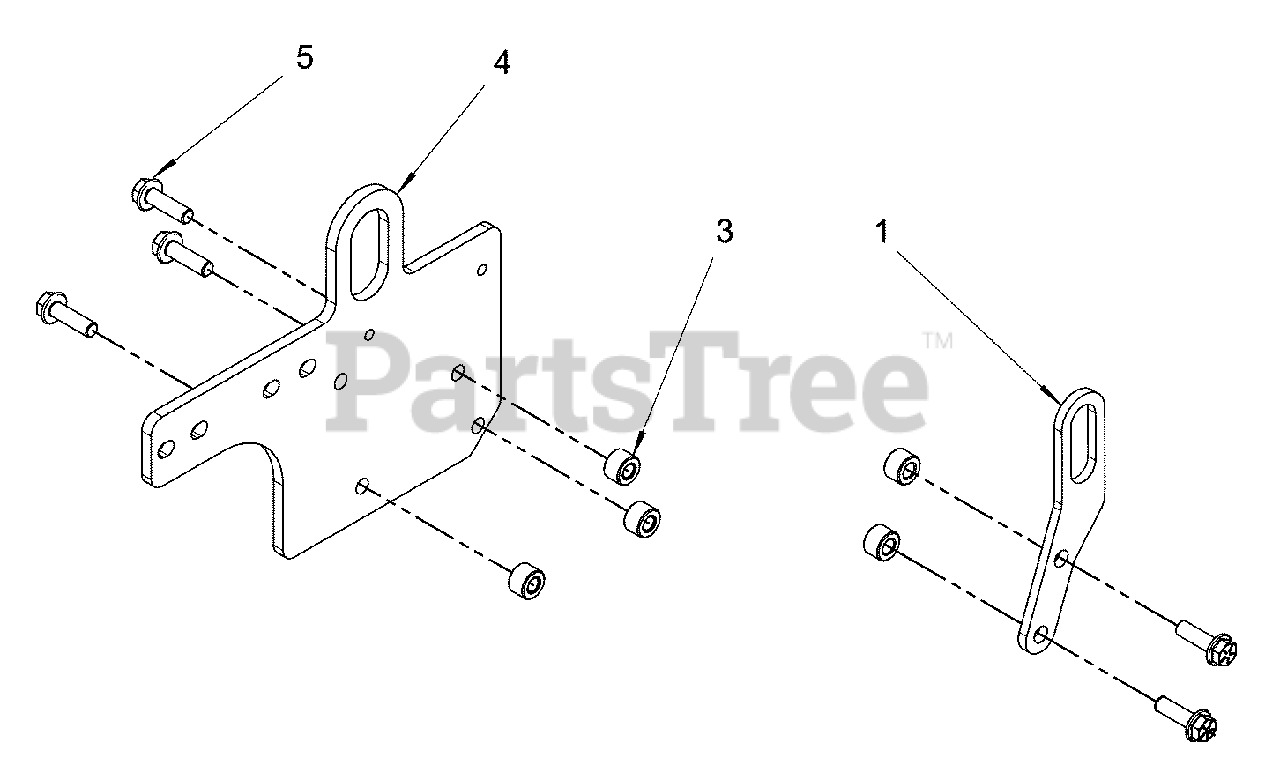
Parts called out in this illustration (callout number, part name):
1	* LIFT EYE BRACKET
3	* SPACER
4	* EXHAUST BRACKET
5	* BOLT
